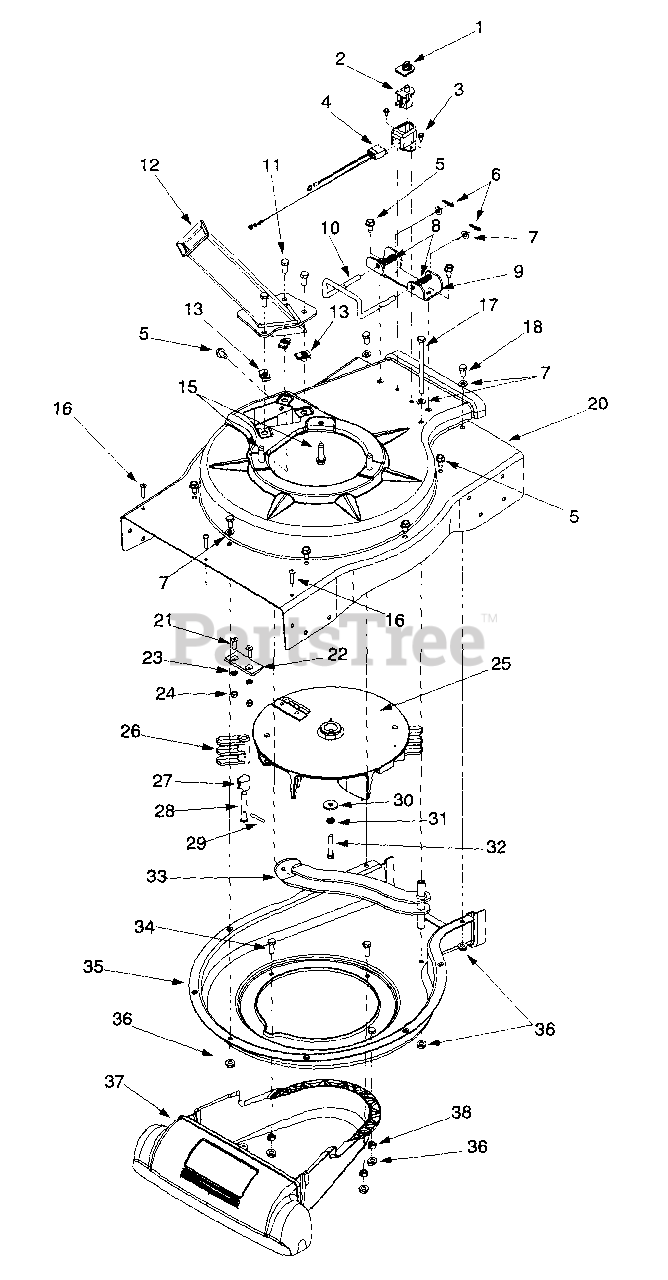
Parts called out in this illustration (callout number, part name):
1	Switch Cover
2	Safety Switch
3	Hex Washer Screw #10-16 x .50
4	Wire Harness
5	Hex Washer Screw 5/16-18 x.625
6	Cotter Pin
7	Flat Washer .330 ID x .630 DD
8	Compression Spring
10	Lock Rod
11	Hex Cap Screw 5/16-18 x .75
13	U-Clip Lock Nut 5/16-16
15	Hex Washer Screw 3/8-16 x 1.25
16	Screw #12-16 x 1.0
17	Hex Cap Screw 5/16-18 x 4.5
18	Hex Cap Screw 5/16-18 x .625
22	Chipper Blade
23	Lock Washer 5/16
24	Hex Lock Nut 5/16-24
25	Impeller Ass'y
26	Flail Blade
27	Pin Clip
28	Clevis Pin
29	Spiral Pin
30	Flat Washer 3/8 ID x 1.25 OD
31	Lock Washer 3/8
32	Hex Cap Screw 3/8-24 x 2.0
34	Hex Cap Screw 5/16-18 x .875
36	Lock Nut 5/16-18
37	Nozzle Cover
38	Lock Nut 5/16-18
